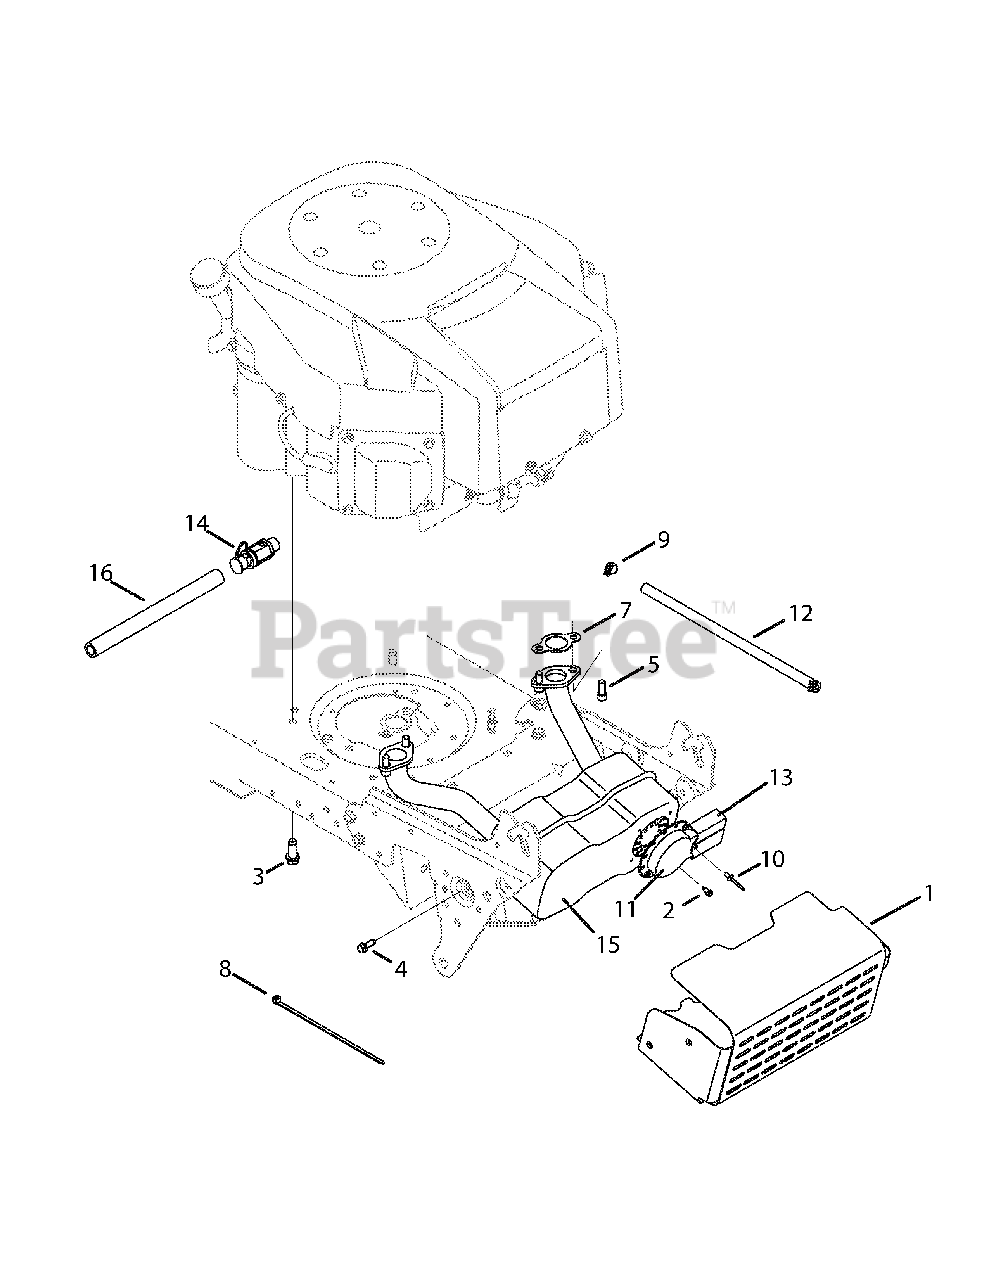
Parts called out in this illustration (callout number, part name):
2	Screw, #8-18, 0.500
3	Screw, Hex, 3/8-16 x 1.00
4	Screw, Hex, 1/4-20, 0.750
5	Screw, 5/16-18, 0.75
6	Sems Nut, 1/4-20
7	Exhaust Gasket, Kohler Twin
8	Cable, Tie, 3/16 x .05 x 7.4
10	Rivet, Pop, .188 x .325
11	Deflector, Muffler
12	Fuel Line, Low Permeation
13	Extension, Deflector
14	Drain, Oil
15	Muffler, Dual Inlet, Kohler
16	Extension Hose, Oil Drain
